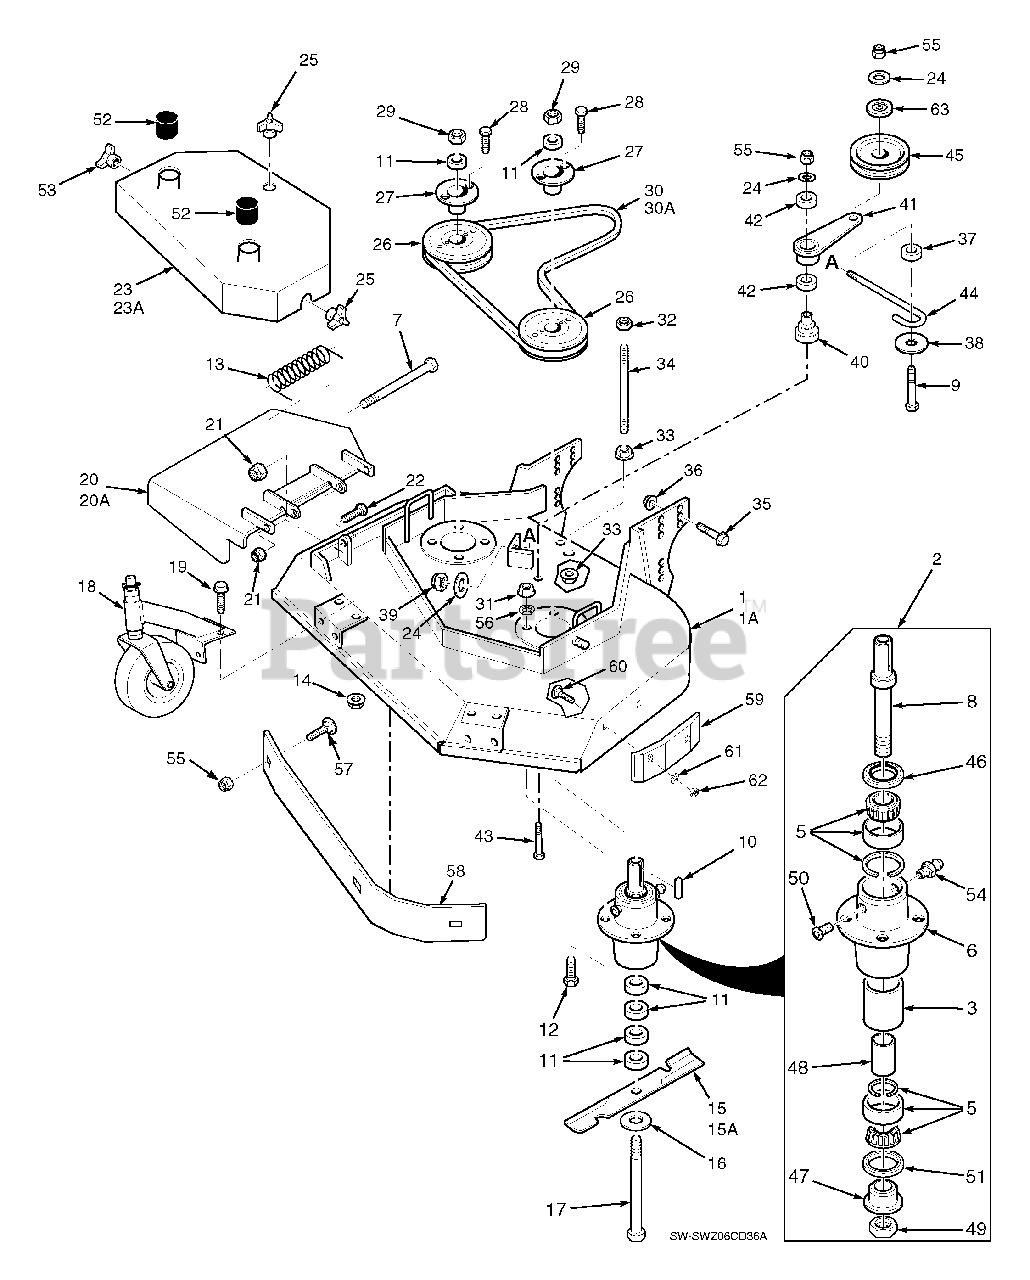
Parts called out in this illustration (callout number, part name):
1	Cutter Deck
1A	Cutter Deck
2	Cutter Spindle Assy.
3	Spacer, Outside
5	Tapered Bearing (Two)
6	Spindle Housing
7	Bolt, 5/16-18 x 4-3/4" Hex Head
8	Spindle Shaft
9	Bolt, 3/8-16 x 3-3/4" Hex Head
10	Key, 1/4 x 1/4 x 2"
11	Spacer, Cutter Blade - Small
12	Bolt, 5/16-18 x 1-1/2" Hex Head Grade 8
13	Spring, Chute Return
14	Nut 5/16-18 Serrated Flange
15	Cutter Blade, 16-1/2" Marbain
15	Cutter Blade, 18" Marbain
15A	Cutter Blade 16-1/2 Hi Lift Marbain
15A	Cutter Blade, 18 Hi Lift Marbain
16	Flatwasher, 5/8 W
17	Hex Hd. Bolt, 5/8-11 x 9-1/2"
18	Caster Assembly
19	Cpscrw,5/16-18 x 3/4" Ser.Flg. Hex Head
20	Discharge Chute
20A	Discharge Chute
21	Hex Nut, 5/16-18 Elastic Stop
22	Hex Hd Bolt, 5/16-18 x 1"
23	Belt Cover Assy
23A	Belt Cover Assy
24	Flat Washer, 3/8" Special
25	Wing Nut, 3/8-16
26	Pulley
27	Tapered Hub
28	Hex Hd. Bolt, 1/4-20 x 1"
29	Hex Nut, 5/8-11
30	Belt, Blade Drive
30A	Belt, Blade Drive
31	Elastic Stop Nut, 5/16-18 Grade 8
32	Hex Nut, 3/8-16 Center Locknut
33	Nut, 3/8-16 Serrated Flange
34	Support, Belt Cover
35	Cpscrw, 1/2-13 x 1" Ser.Flg. HH
36	Nut, 1/2-13 Spiralock
37	Spacer, J-Hook
38	Flatwasher, 3/8 x 1-1/2 x 16 GA
39	Elastic Stop Nut, 3/8-16
40	Idler Pivot
41	Idler Arm Assy.
42	Bearing
43	Cpscrw, 3/8-16 x 3-1/4" Hex Head
44	J-Hook
45	Idler Pulley, Belt Clutch
46	Seal, Cutter Spindle
47	Spindle Bushing
48	Spacer, Inside
49	Nut,1.06-18
50	Relief Fitting, Cutter Spindle
51	Seal, Cutter Spindle
52	Spindle Shield
53	Wing Nut, 3/8-16 (Small) RH side
54	Grease Fitting
55	Nut, Hex Elastic Stop 3/8-16
56	Lock Washer, 5/16"
57	Bolt, Carriage 3/8-16 x 1"
58	Baffle Weldment
59	Pad, Deck Wear
60	Bolt, Carriage 5/16-18 x 3/4"
61	Flatwasher, 5/16"
62	Hex Nut, 5/16-18 Center Locknut
63	Dust Shield
